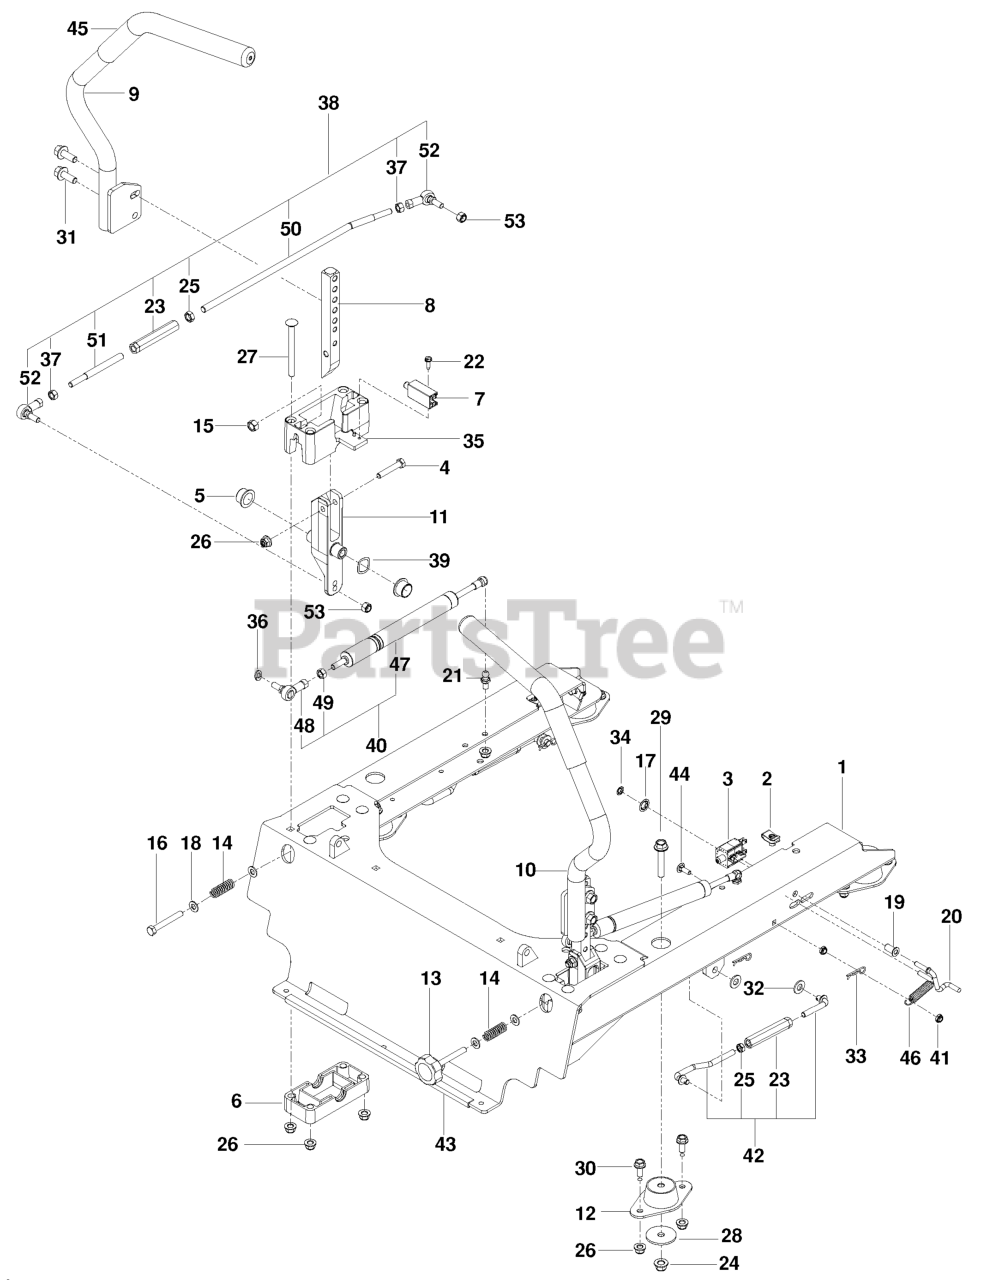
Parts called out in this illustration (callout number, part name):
1	FRAME.SEAT.MOUNT.ORANGE
2	U-CLIP 5/16-18 NUT RETAINER
3	SWITCH, BRAKE 3P
4	HCS 5/16C X 1 3/4
5	BEARING, FLANGE
6	BLOCK, LOWER
7	SWITCH, INTERLOCK
8	LEVER, MOTION
9	LEVER, W/GRIP, RT
10	LEVER, W/GRIP, LT
11	LEVER, CONTROL
12	MOUNT, ISO
13	KNOB
15	NUT 5/16C HEX
16	HCS 5/16-18 X 2 1/2 TPBLT
17	NUT 3/8 PALNUT RTNG BLK PHOS
18	FLAT WASHER 5/16 SAE
19	BUSHING, 1/4 FLANGE
20	LINK, SWITCH
21	STUD.BALL.10MM
22	SCREW #10 X 1/2 SELF TAPPING
23	TURNBUCKLE, 3/8
24	NUT 3/8-16 HEX FLG NYLOC ZD
25	NUT 3/8-24 JAM
26	5/16-18 NYLOC FLANGE NUT
27	RHSNB 5/16-18 X 3-3/4 GR 5 ZD
28	WASHER, 3/8 SPEC
29	HHFS 3/8-16 X 2.0 GD 5
30	HHFS 5/16-18 X 3/4
31	HHFS 3/8-16 X 1 GRD 5 ZD
32	WASHER 3/8 SAE FLAT
33	HAIRPIN #2
34	NUT PUSH
35	BLOCK, UPPER
36	WASHER.LOCK.HVY.HLCL.SPR.5/16
38	LINKAGE, CONTROL, DIESEL
39	WASHER, .825 X 1.087, WAVE
40	ASSEMBLY, DAMPENER
41	JAM NUT 1/4C (2 2 PW01)
42	ASSEMBLY, SEAT STRUT
43	RP.FLEX TRIM, BLK-LENGTH 1 FT
44	RHSNB 1/4C X 3/4
45	GRIP - DRIVE LEVER 12"
46	SPRING, EXTENSION
49	NUT M8 X 1.25 STD HEX
50	LINKAGE, CONTROL, FT
51	LINKAGE, CONTROL
52	SPHERICAL ROD END, RH
53	NUT 5/16F NYLOC
